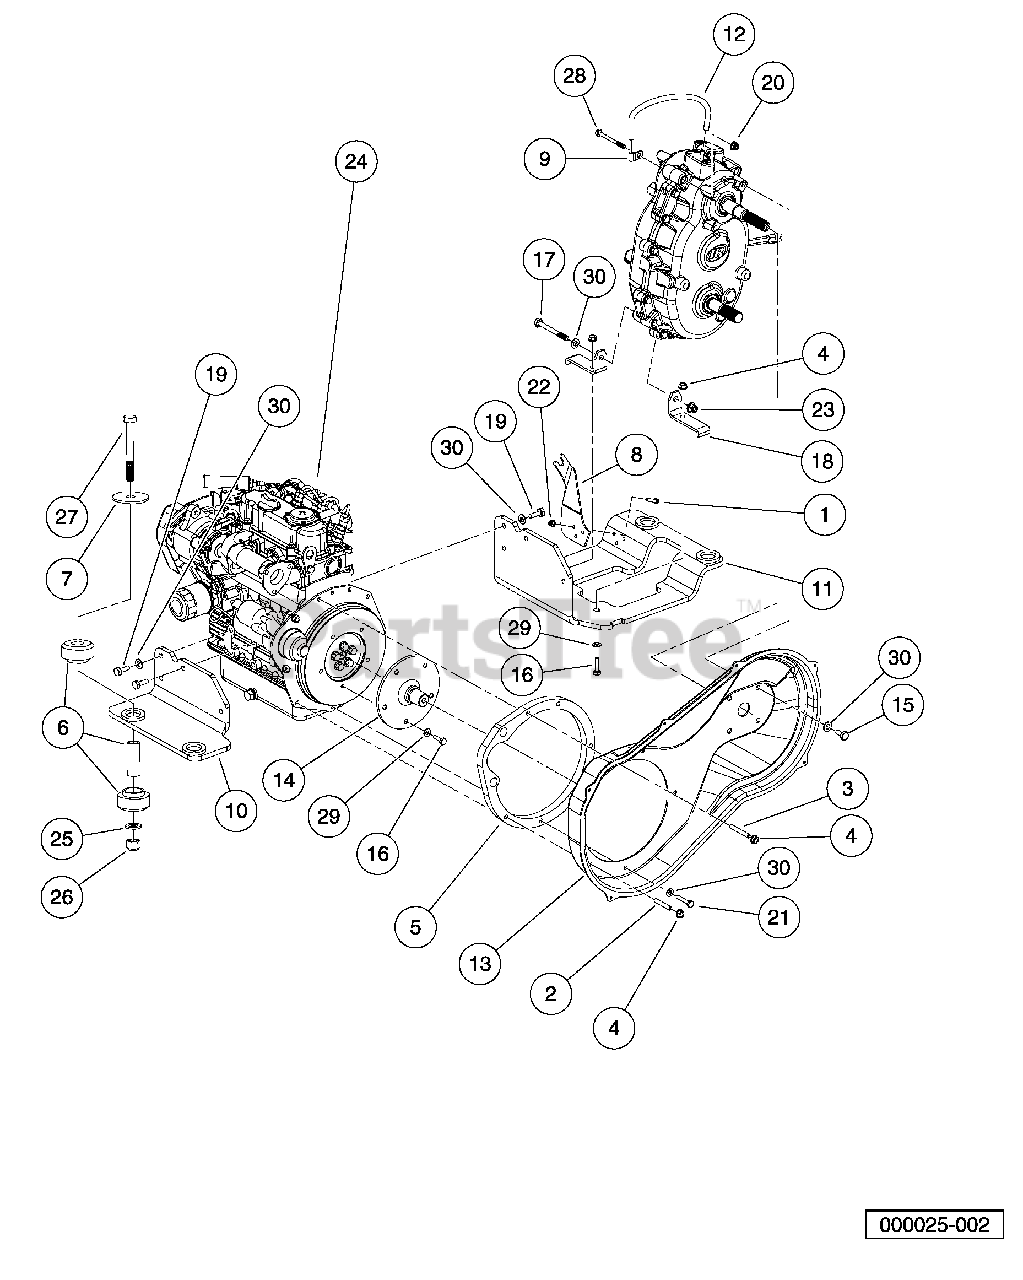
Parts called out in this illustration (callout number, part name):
1	Screw, M6-1.00 X 25mm Hex Cap
2	Stud, M8-1.25 X 50 mm Two-Ended
3	Stud, M8-1.25 X 60mm Two-Ended
4	Nut,m8,all Metal Lock
5	Spacer, Engine, Diesel
6	Isolator Ring and Bushing
7	Washer, Snubbing, Ring N Bush
8	Bracket, FNR Trans Cable
9	P-Clamp, Insulated .312 In
10	Plate, Engine Mounting, Weld, Left-Hand
11	Plate, Engine Mounting, Weld, Right-Hand
12	Hose, Vent, Transmission
13	Cover, CVT Inner, Diesel
14	Shaft, CVT Adapter
15	Bolt, M10 X 1.5 X 20 Loctite
16	Bolt, M8 X 1.25 X 25 Loctite
17	Bolt, M10 X 1.5 X 100 Loctite
18	Bracket, Transmission Mounting
19	Bolt, M10 X 1.25 X 25 Loctite
20	Lock Nut, Flg M8 X 1.25 Nylon
21	Bolt, M8 X 1.25 X 40 with Loctite
22	Nut Flg, M6 X 1.0 Nylon
23	Nut Flg M10 X 1.5 Nylon
24	Engine, Kubota, D722, with Closed Breather, 60a
25	Washer, M12 Hard
26	Locknut, M12x1.75 Nylon Insert
27	Bolt, M12 X 1.75 X 90
28	Bolt, M8 X 1.25 X 80
29	Washer, M8 Hard
30	Washer, M10 Hard
